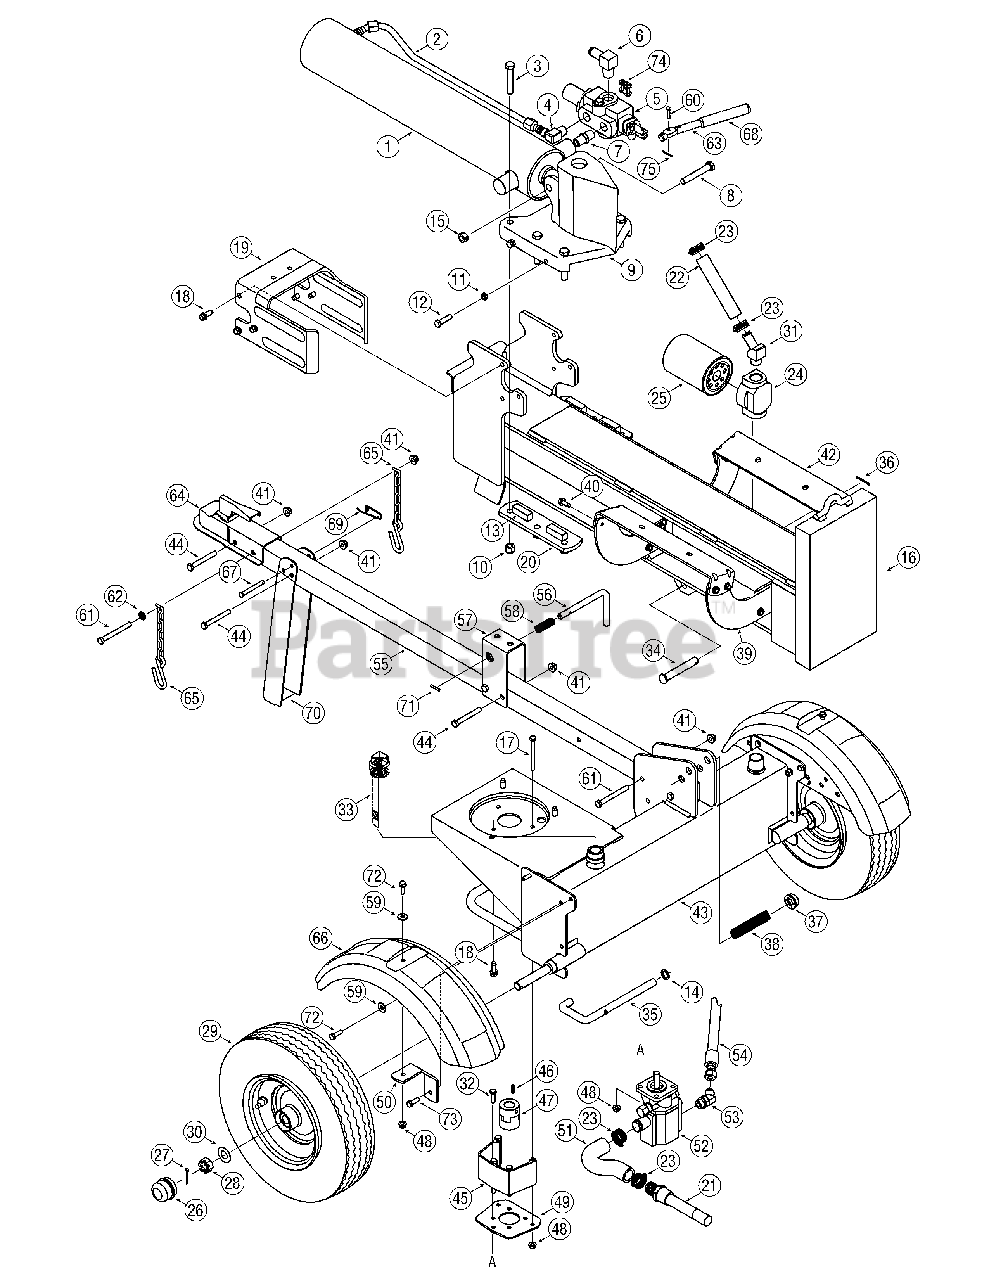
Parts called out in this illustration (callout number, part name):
1	Hydraulic Cylinder
1	Kit Seal 4.5" for XINGHUI cylinder
1	Kit Seal 4.5" for ENERGY cylinder
2	Hydraulic Tube
3	Hex Cap Screw 1/2-20 x 2.75
4	90 Degree Solid Adapter
5	Control Valve
6	Return Elbow
7	Nipple Pipe 1/2-14
8	Hex Cap Screw 1/2-13 x 3.25
9	Wedge Assembly
10	Hex Lock Nut, 1/2-20
11	Hex Jam Nut 3/8-24
12	Hex Cap Screw 3/8-24 x 1.5
13	Adjustable Gib
14	Flat Washer.635 x.93 x.06
15	Hex Lock Nut 1/2-13
17	Hex Screw, 5/16-18 x 3.25
18	Hex Washer Screw 3/8-16 x 1.0
21	Inlet Filter
22	Return Hose 3/4" ID x 44" Lg.
23	Hose Clamp 5/8"
24	Filter Housing
25	Oil Filter
27	Cotter Pin
28	Slotted Nut 3/4-16
29	Wheel Assembly
30	Flat Washer.760 ID x.500 OD
31	Adapter 3/4-14
32	Hex Screw, 5/16-18 x 1.00
33	Vented Dipstick
34	Clevis Pin
36	Cotter Pin
38	Compression Spring
40	TT Screw, 5/16-18 x.875
41	Flange Lock Nut, 3/8-16
43	Frame Assembly
44	Hex Bolt 3/8-16 x 3"
45	Coupling Shield
46	Square Key 3/16" x.75
47	Flexible Coupling
48	Flange Lock Nut, 5/16-18
52	Gear Pump
53	45 Degree Elbow Fitting
54	High Pressure Hydraulic Hose
56	Latch Rod
58	Compression Spring
59	Flat Washer
60	Clevis Pin
61	Hex Cap Screw, 3/8-16 x 3.50
62	Flat Washer,.375 x.738 x.063
63	Hydraulic Valve Control
64	Hitch Coupling Assembly
66	Fender (Black)
67	Clevis Pin
69	Spring Pin
72	TT Screw, 5/16-18 x 0.875"
73	TT Screw, 5/16-18 x 1.00
74	Valve Handle Link
75	Cotter Pin
